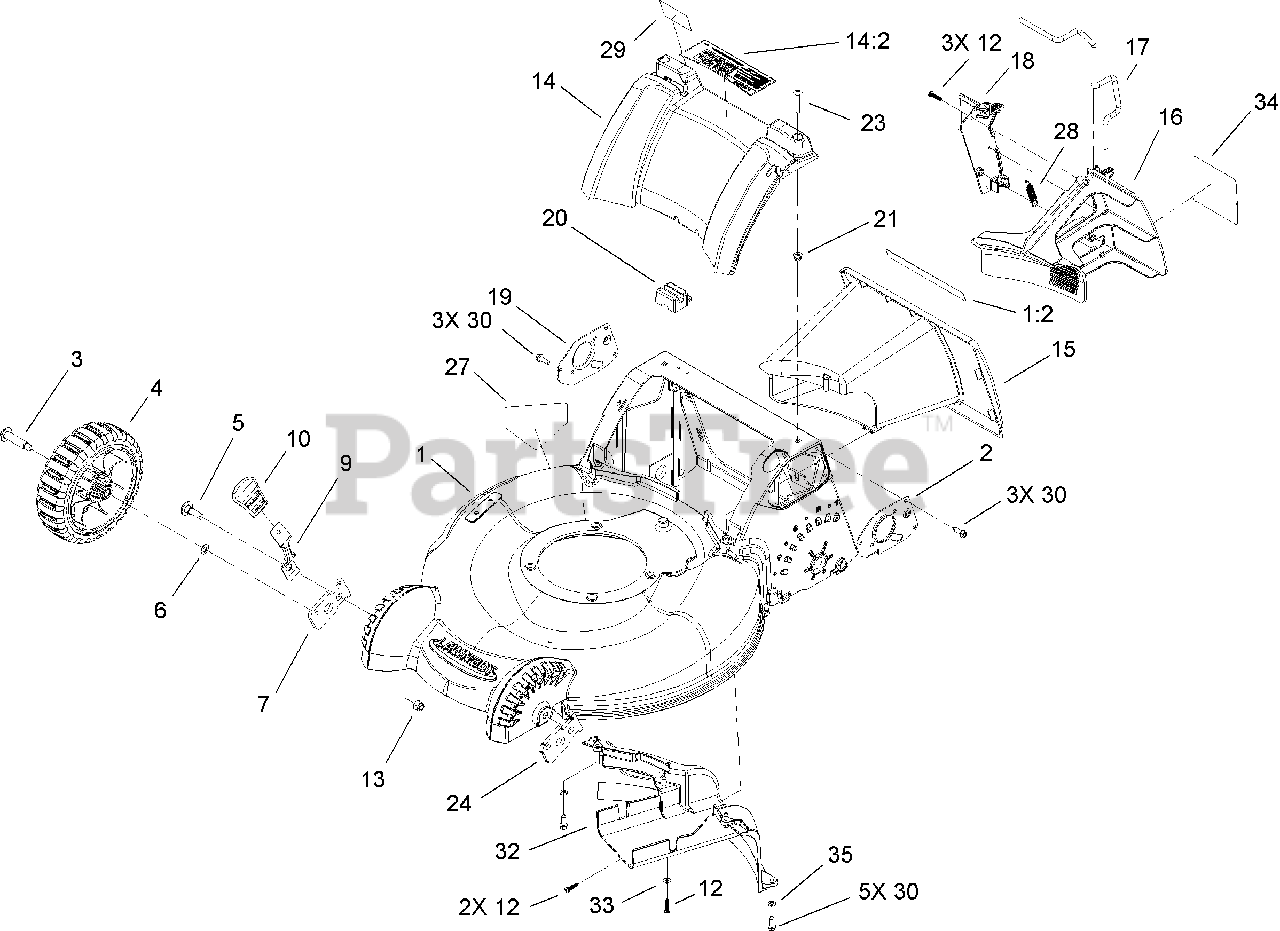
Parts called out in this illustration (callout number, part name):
1	HOUSING ASM
1:2	DECAL-SAFETY, BAG
2	MOUNT-HANDLE, LH
3	BOLT-SHOULDER
4	8 INCH WHEEL ASM
5	BOLT-SHOULDER
7	ARM-PIVOT, RH
9	ARM-SPRING, FRONT
12	SCREW-PLASTITE
13	NUT-LOCK, NI
14	COVER-REAR
14:2	DECAL-SAFETY
16	PLUG-MULCH, LH
17	LATCH-MULCH PLUG
18	PLUG-MULCH, RH
19	MOUNT-HANDLE, RH
20	MODULE-SWITCH
21	NUT-CLIP
23	SCREW-PTH
24	ARM-PIVOT, LH
27	DECAL-DANGER
28	SPRING-EXTENSION
29	DECAL-BAG ATTACHMENT
30	SCREW-HWHTF
32	BAFFLE-REAR
33	WASHER-FLAT
34	DECAL-MULCH PLUG
35	WASHER-FLAT
